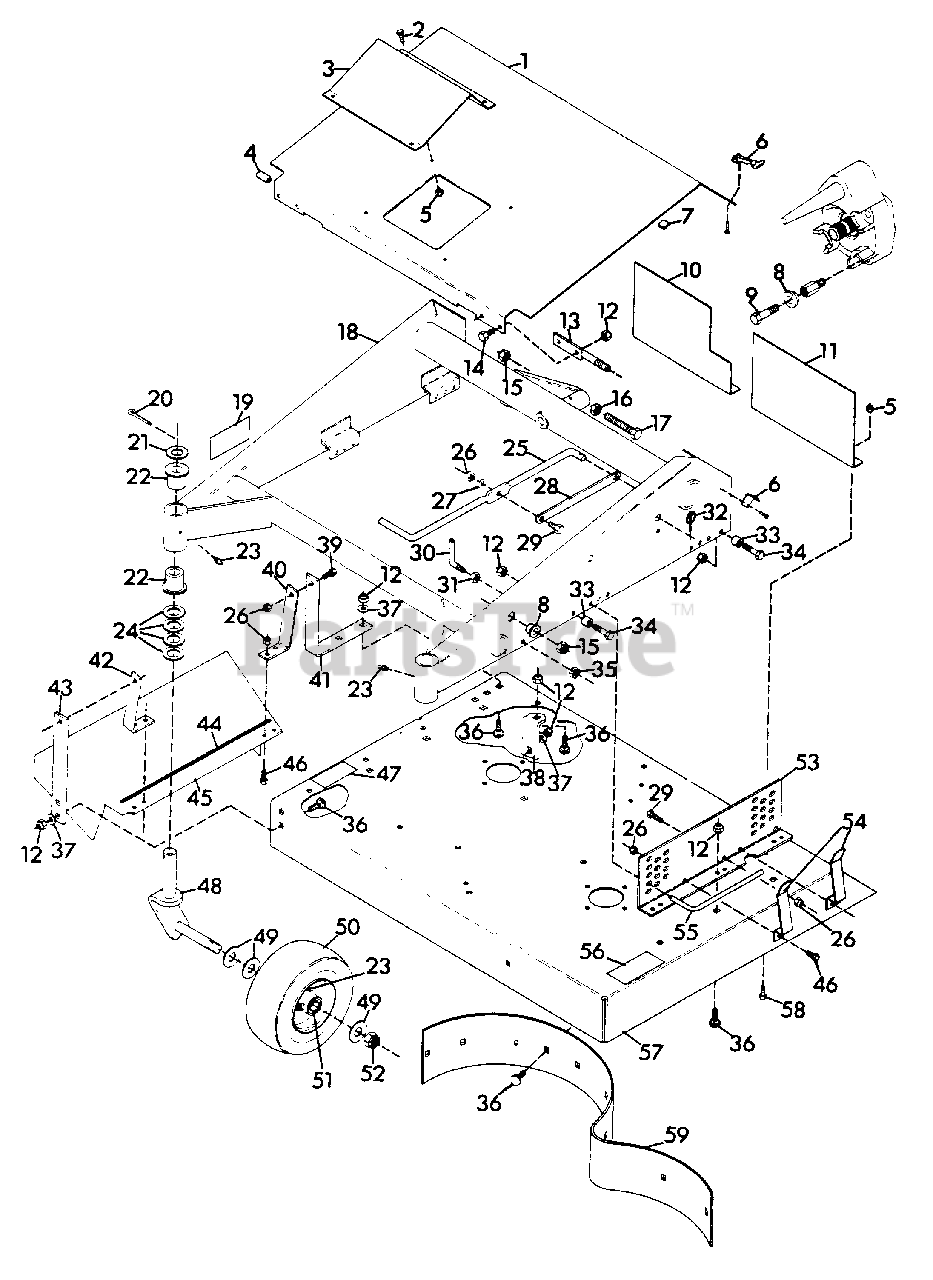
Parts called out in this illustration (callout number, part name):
1	Shield
2	Bolt, Hex 1/4-20x.625
3	Cover, Hole
4	Strip, Bumper
5	Nut, Lock 1/4-20
6	Latch, Flexible Draw
7	Stop
8	Bushing, .513x.750x.625
9	Bolt, Hex 1/2-13x1.50
10	Shield, Rear R.H.
11	Shield, Rear L.H.
12	Nut, Lock 3/8-16
13	Bracket, Hinge
14	Bolt, Hex 3/8-16x.875
15	Nut, Lock 1/2-13
16	Nut, Jam 1/2-13 Hex
17	Bolt, Hex 1/2-13x3.00 All Thd.
18	Weldment, Mower Frame
19	Decal, Danger Hand
20	Pin, Cotter .187x1.50
21	Race, Bearing Thrust
22	Bushing, Pivot
23	Fitting, Lube 1/4-28
24	Washer, Flat 1.0x1.5x.125
25	Handle, Lift
26	Nut, Lock 5/16-18
27	Washer, Flat .344x.688x.065
28	Strap, Lift
29	Bolt, Hex 5/16-18x1.00
30	Handle, Adjusting
31	Nut, Hex 3/8-16
32	Pin, Klik
33	Bushing .391x.622x.670
34	Bolt, Hex 3/8-16x1.50
35	Nut, Lock 3/8-16
36	Bolt, 3/8-16x1.00 Rd Hd Sq Nk
37	Washer, Flat .406x.812x.065
38	Bracket
39	Bolt, Hex 5/16-18x1.25
40	Bracket, Chute Rear
41	Bracket
42	Bracket, Chute Front
43	Bracket
44	Stripe,
45	Chute, Discharge
46	Bolt, Hex 5/16-18x.75
47	Decal, Warning Eye
48	Weldment, Caster Fork
49	Washer, Flat .812x1.496x.134
50	Wheel, Gauge
51	Bearing, Gauge Wheel
52	Nut, Lock 3/4-10
53	Bracket, Mower Support
54	Spring, Pin
55	Pin, Mower Locking
56	Decal, Danger Foot
57	Weldment, 36" Deck
58	Bolt, Hex 1/4-20x.750
59	Scroll
